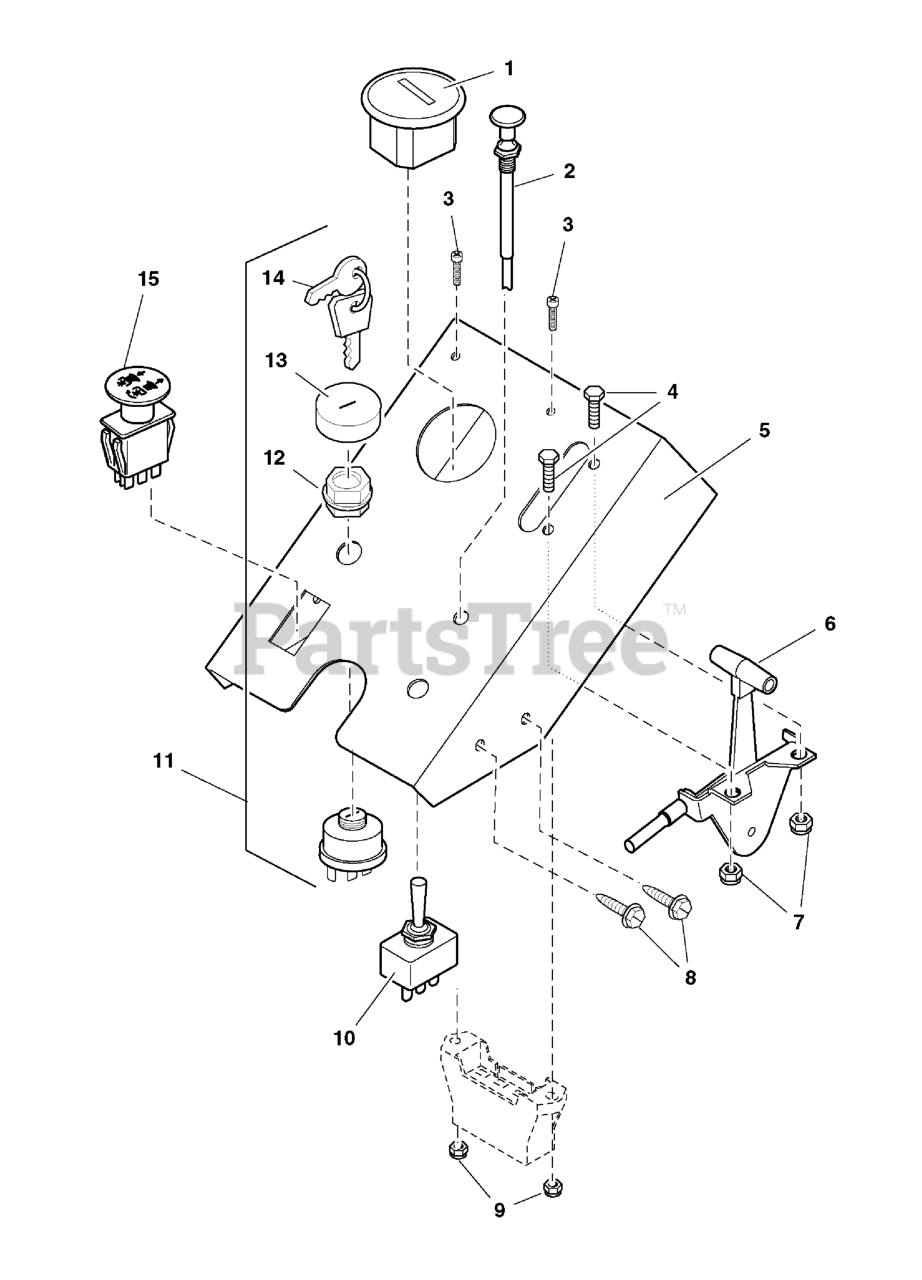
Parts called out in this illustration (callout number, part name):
1	HOUR METER
2	CABLE, Choke Control, 57"
3	SCREW, #10-24 X 1 RS, CZ
4	BOLT, 1/4-20 x 3/4
5	DASH PANEL
6	CABLE, Throttle, 54"
7	NUT, 1/4-20 HEX NYLON LOCK
8	BOLT, Self-Tapping, 1/4-20 x 3/4
9	NUT, #10-24 Hex Nylon Lock
10	SWITCH, Actuator
11	SWITCH, IGNITION, 6 POST
12	PLASTIC NUT
13	COVER, PLASTIC, SNAP ON
14	KEY, IGNITION MOLDED SET
15	SWITCH, BLADE ENGAGEMENT
